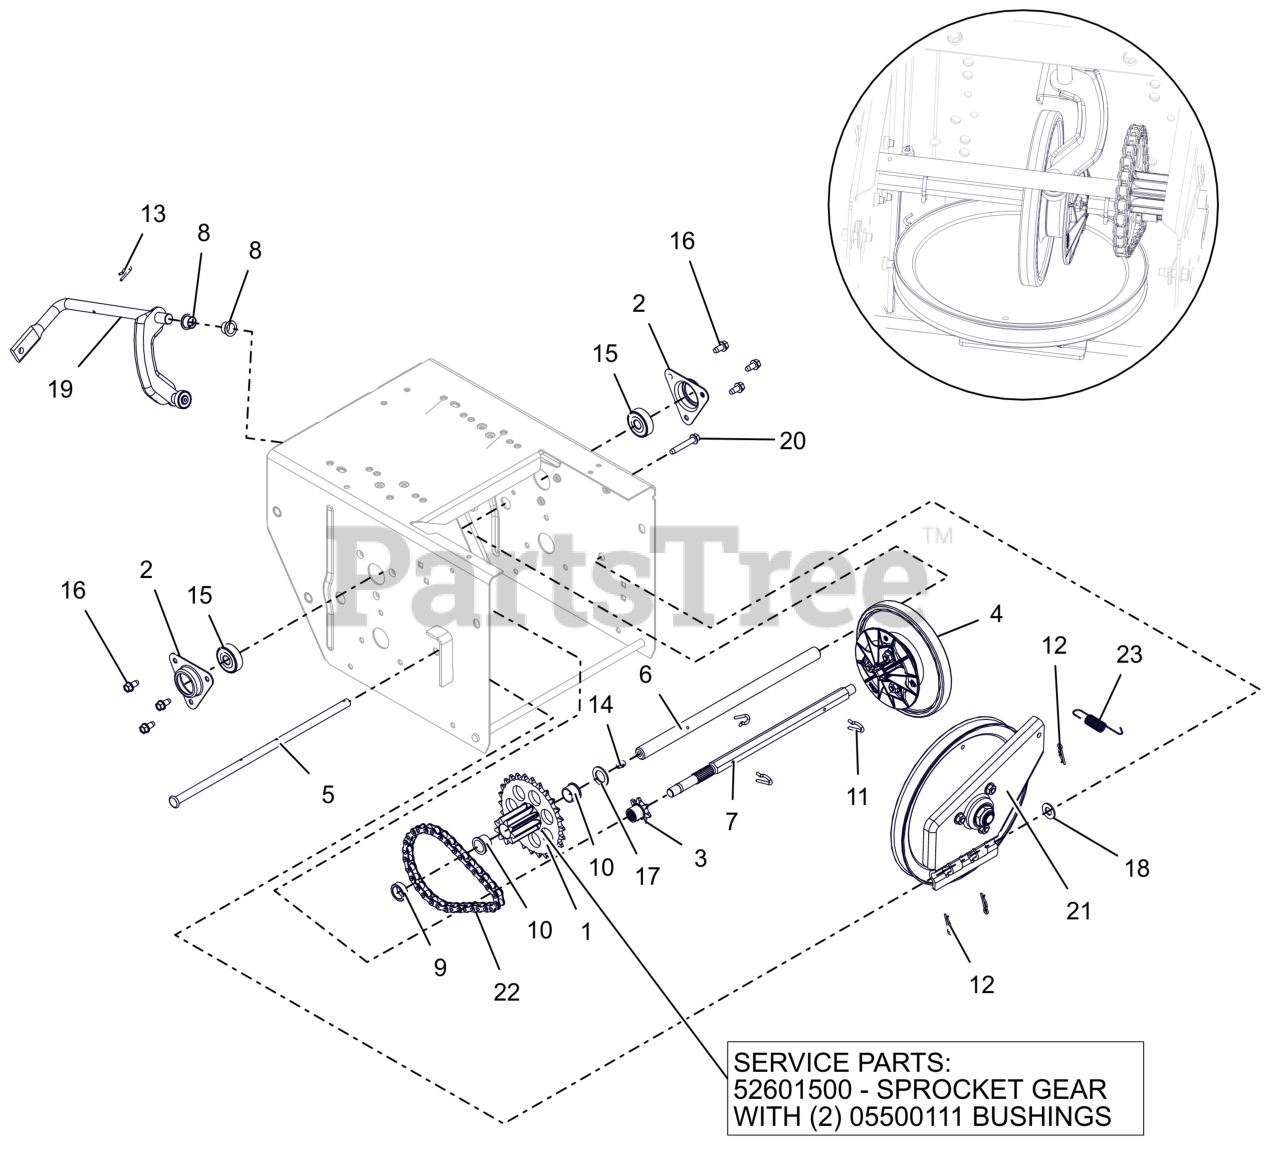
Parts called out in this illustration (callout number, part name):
1	PINION & SPROCKET
1	PINION & SPROCKET W/BUSHINGS
2	FLANGE, BEARING
3	SPROCKET, PINION 7T W/SPLINE
4	DISC, FRICTION DRIVE-ASSEMBLY
5	PIN, PIVOT
6	SHAFT, PINION
7	SHAFT, HEX
8	BUSHING, POLYLINER-.50 SPLIT
9	BSHG-SLV, .635X.880X.305
10	BSHG-FLG .625X.750X.500X.875
11	PIN, SPRING CLIP
12	PIN, HAIR #225 .072X1.09
13	CLIP, SPRING
14	ZERK,FITTING .25X.125 DRIVE IN
15	BRG-BALL .437X1.375X.437
16	SCR-TAP .25-20X.50 HWH ZCC
17	WSHR, FLT .630X1.005X.062 ZCC
18	WSHR,FLT .406X.812X.065 ZCC
19	ARM, SHIFT - ASSEMBLY
20	SCR,TAP .25-20X1.50 HWH TR ZCC
21	PLATE, SWING ASSEMBLY-DEEP
22	CHAIN - #41, 32 PITCHES
23	SG-TENS .048X.50X2.8
